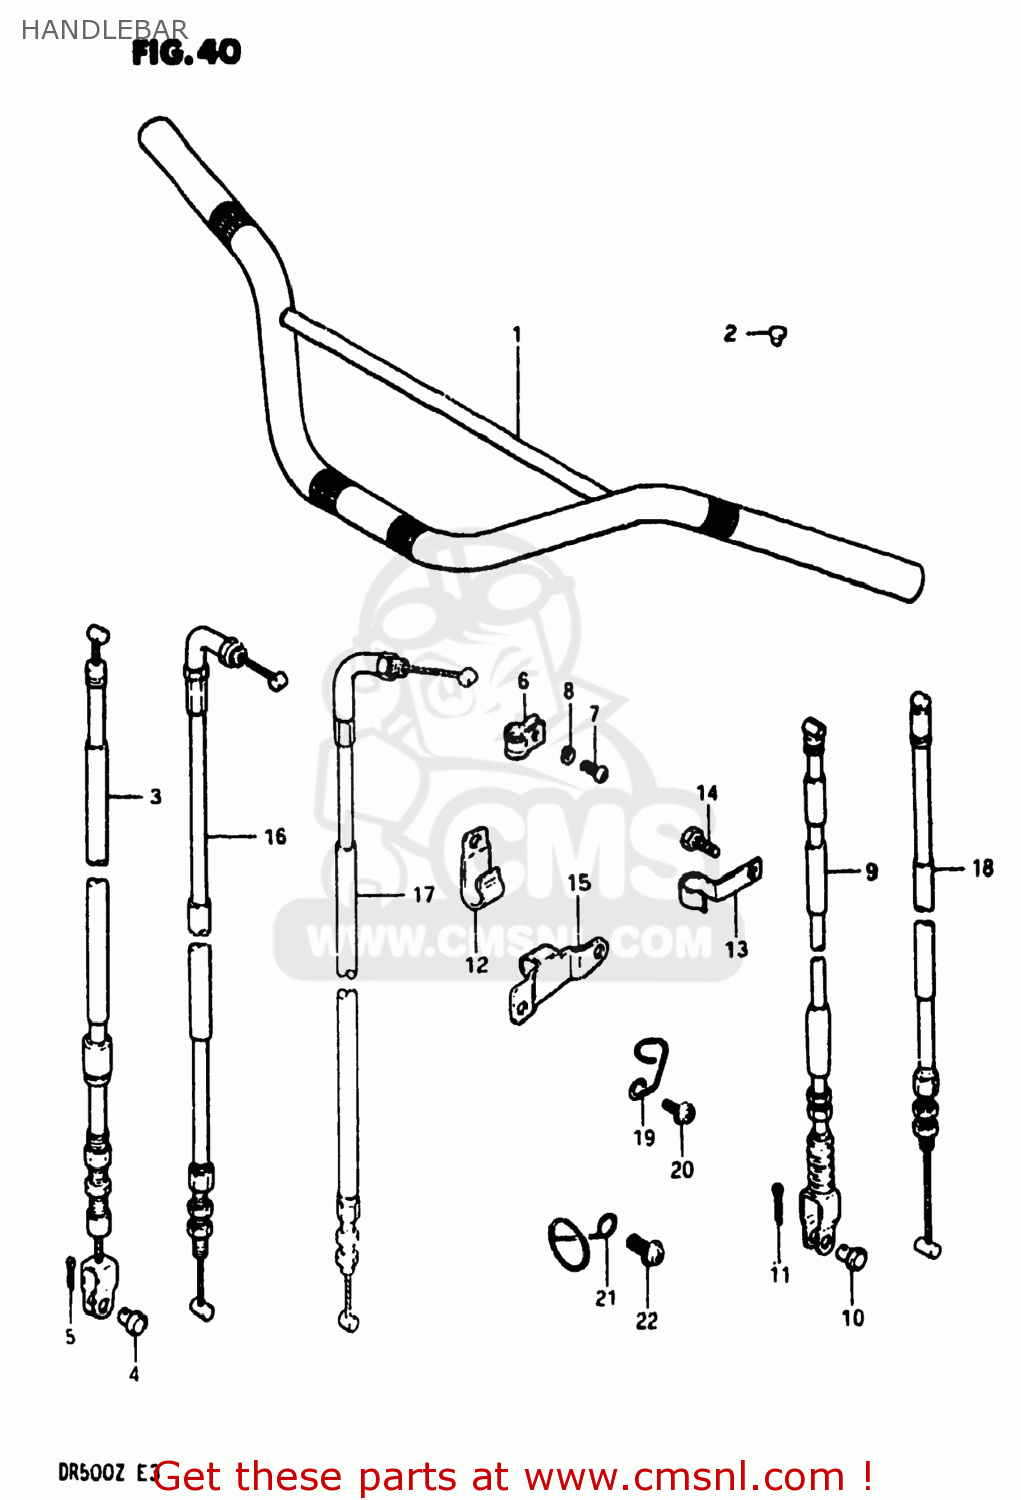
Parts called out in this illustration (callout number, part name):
1	HANDLEBAR
2	CAP(OD:14)
3	CABLE ASSY,FR BRAKE
5	PIN
6	PIN(L:17.5)
7	SCREW
8	LOCK WASHER
9	CABLE ASSEMBLY,CLUTCH
10	PIN(L:15)
11	PIN
12	CLAMP
13	CLAMP,CLUTCH CABLE NO.1
14	BOLT
15	STOPPER,CLUTCH CABLE
16	CABLE ASSY,THROTTLE NO.1
17	CABLE ASSEMBLY,THROTTLE NO
18	CABLE ASSY,DECOMP
19	GUIDE
20	SCREW
21	GUIDE,CABLE
22	SCREW, FRONT
